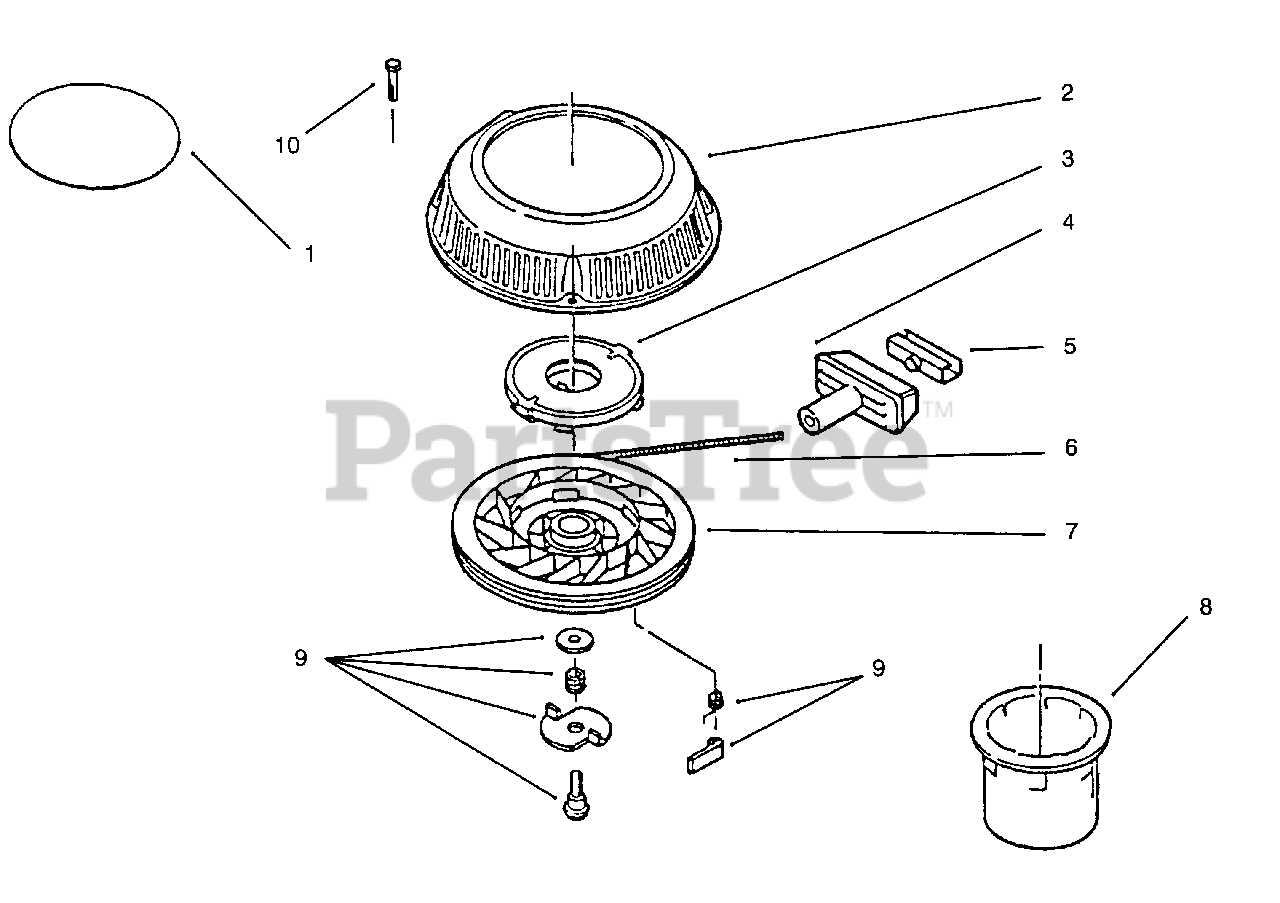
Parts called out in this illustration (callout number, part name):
1	Decal-Recoil
2	Starter Housing & Shaft
3	Spring & Keeper
4	Handle-Starter
5	Clip-Rope
6	Rope
8	Hub-Starter
9	Kit-Dog
10	Screw-Starter Mtg.
